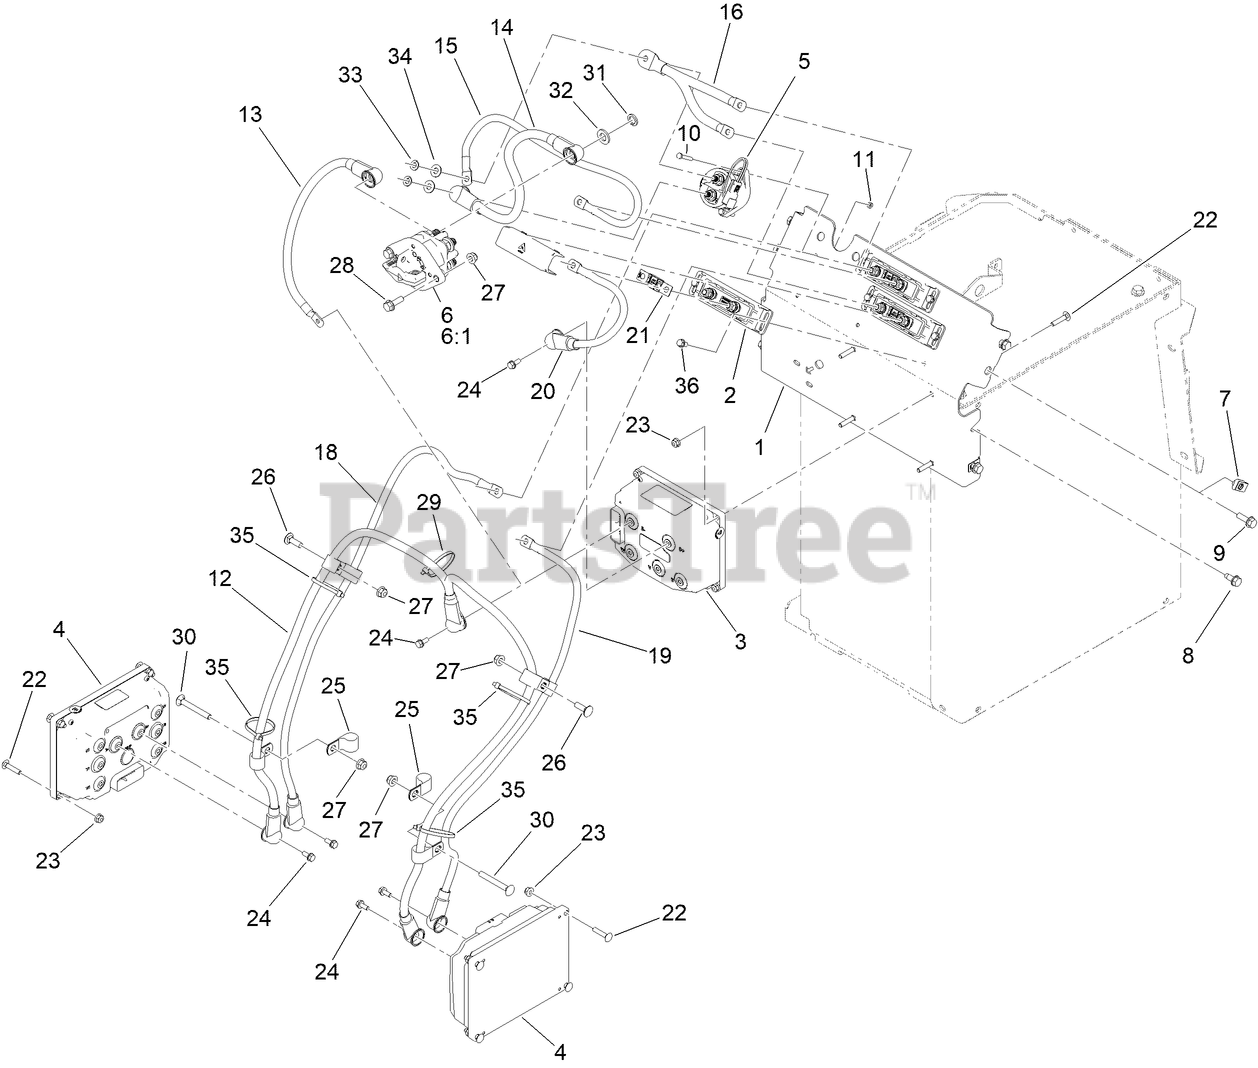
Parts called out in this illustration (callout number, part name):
1	BRACKET-MOUNT,INVERTER
2	HOLDER-FUSE
3	INV/CTRLR-48V,185ARMS
4	INV/CTRLR-48V,DUAL 94Arms
5	CONTACTOR-48V
6	SWITCH-DISCONNECT
6:1	NUT-HF
7	NUT-U
8	SCREW-THD ROLL, HWH
9	SCREW-HHF
11	NUT-LOCK
12	CABLE-BATTERY, BK ASM
13	CABLE-BATTERY, BK ASM
14	CABLE-BATTERY, RD ASM
15	CABLE-BATTERY, RD ASM
16	CABLE-BATTERY, RD ASM
18	CABLE-BATTERY, RD ASM
19	CABLE-BATTERY, RD ASM
20	CABLE-BATTERY, RD ASM
21	FUSE-200A
22	SCREW-CARR
23	NUT-FLANGE, NI
24	SCREW-SEMS
25	CLAMP-R
26	BOLT-CARR
27	NUT-HF, NI
28	SCREW-HHF
29	TIE-CABLE
30	SCREW-CARR
31	SPLIT LOCK WASHER,1/2,ST/ST,18-8
32	WASHER-FLAT
33	WASHER-LOCK
34	WASHER
35	TIE-CABLE
36	SCREW-HWH
